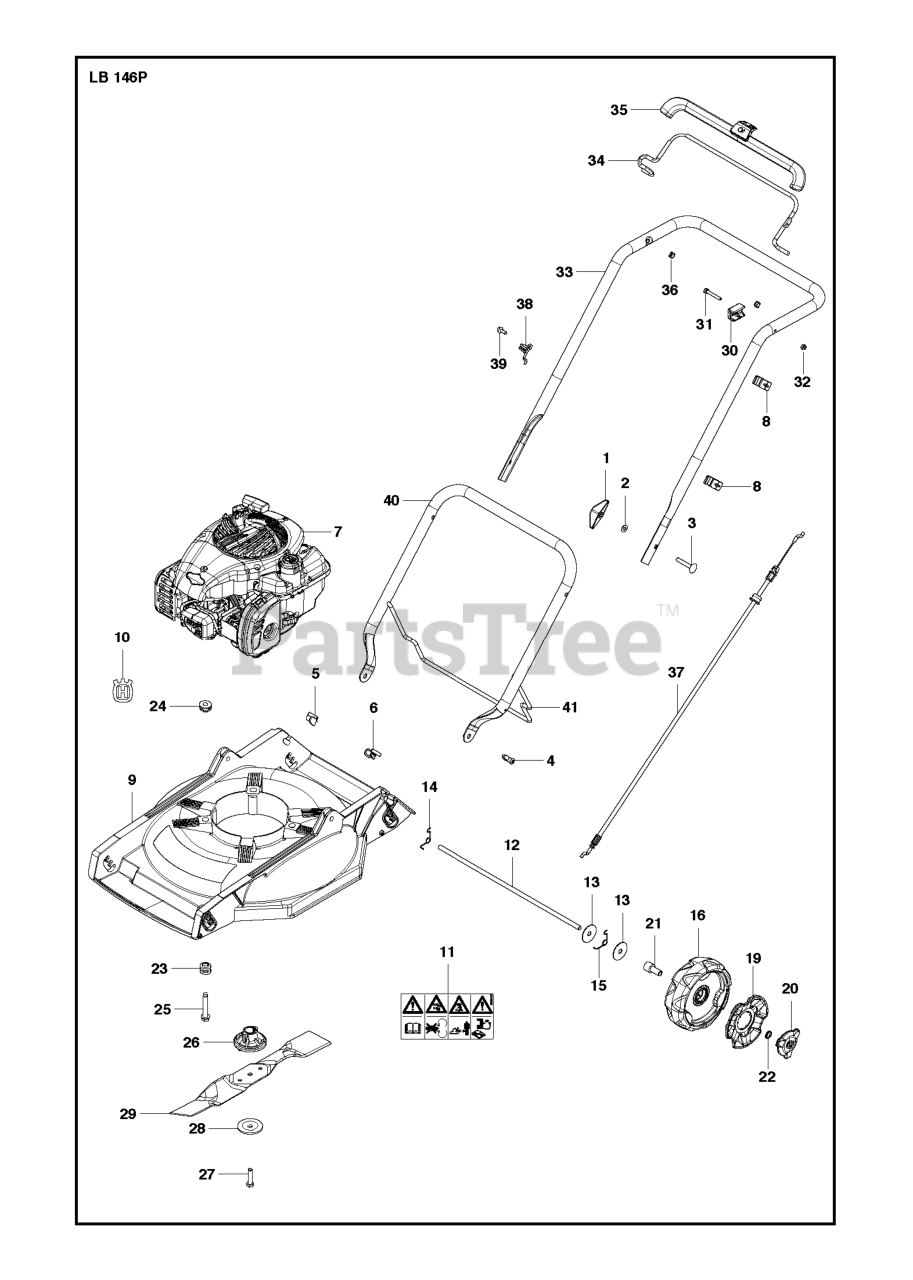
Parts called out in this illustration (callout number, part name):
1	WINGNUT
10	DECAL HUSQVARNA CROWN 41MM FLA
32	NUT FLANGE - M6
39	SCREW
